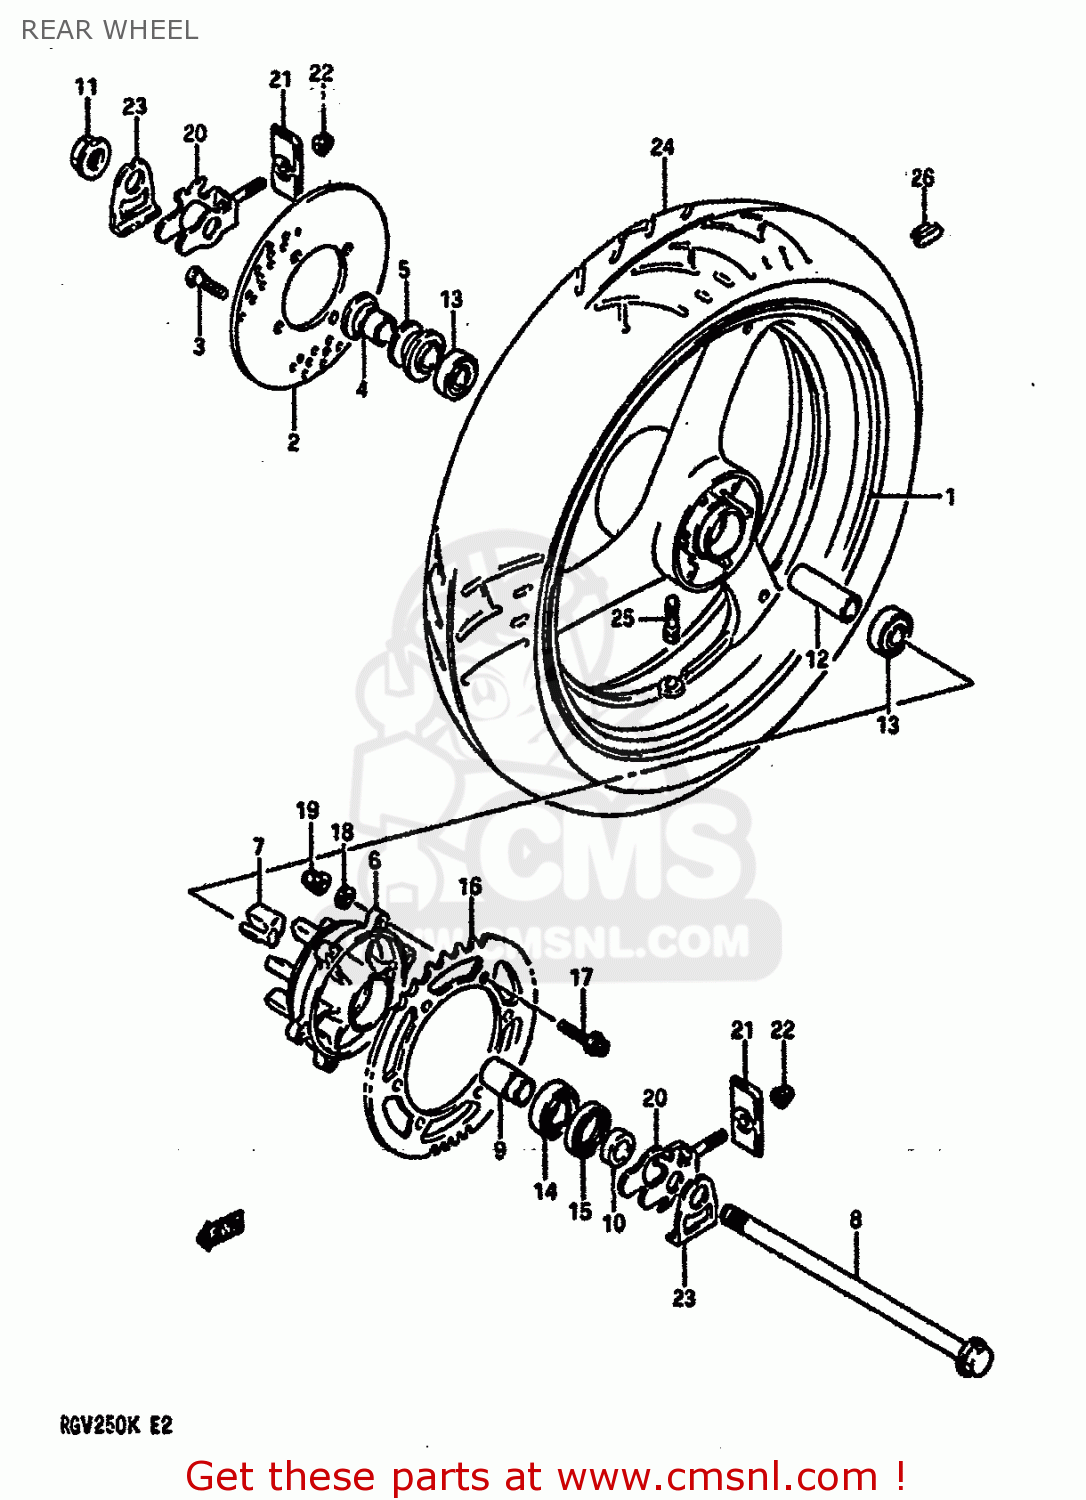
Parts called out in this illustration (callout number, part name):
1	WHEEL,REAR (NT4.00X18) WHITE
2	DISK,REAR BRAKE
3	BOLT 8X33
4	SPACER,CALIPER BRACKET
5	SPACER,RR AXLE,R
6	DRUM,REAR SPROCKET
7	CUSHION,REAR DRUM
8	AXLE,REAR
9	RETAINER,RR SPROCKET DRUM
10	SPACER,REAR AXLE LH
11	NUT
12	SPACER,RR WHEEL BEARING
13	BEARING(20X47X14)
14	BEARING
15	SEAL,OIL(34X54X8)
16	SPROCKET,REAR (NT:46)
17	BOLT, REAR
18	WASHER
19	NUT
20	ADJUSTER,CHAIN
21	PLATE,GUIDE
22	NUT
23	WASHER,CHAIN ADJUSTER
24	TIRE,REAR (140/60R18)
25	VALVE,TIRE
26	BALANCER,WHEEL
